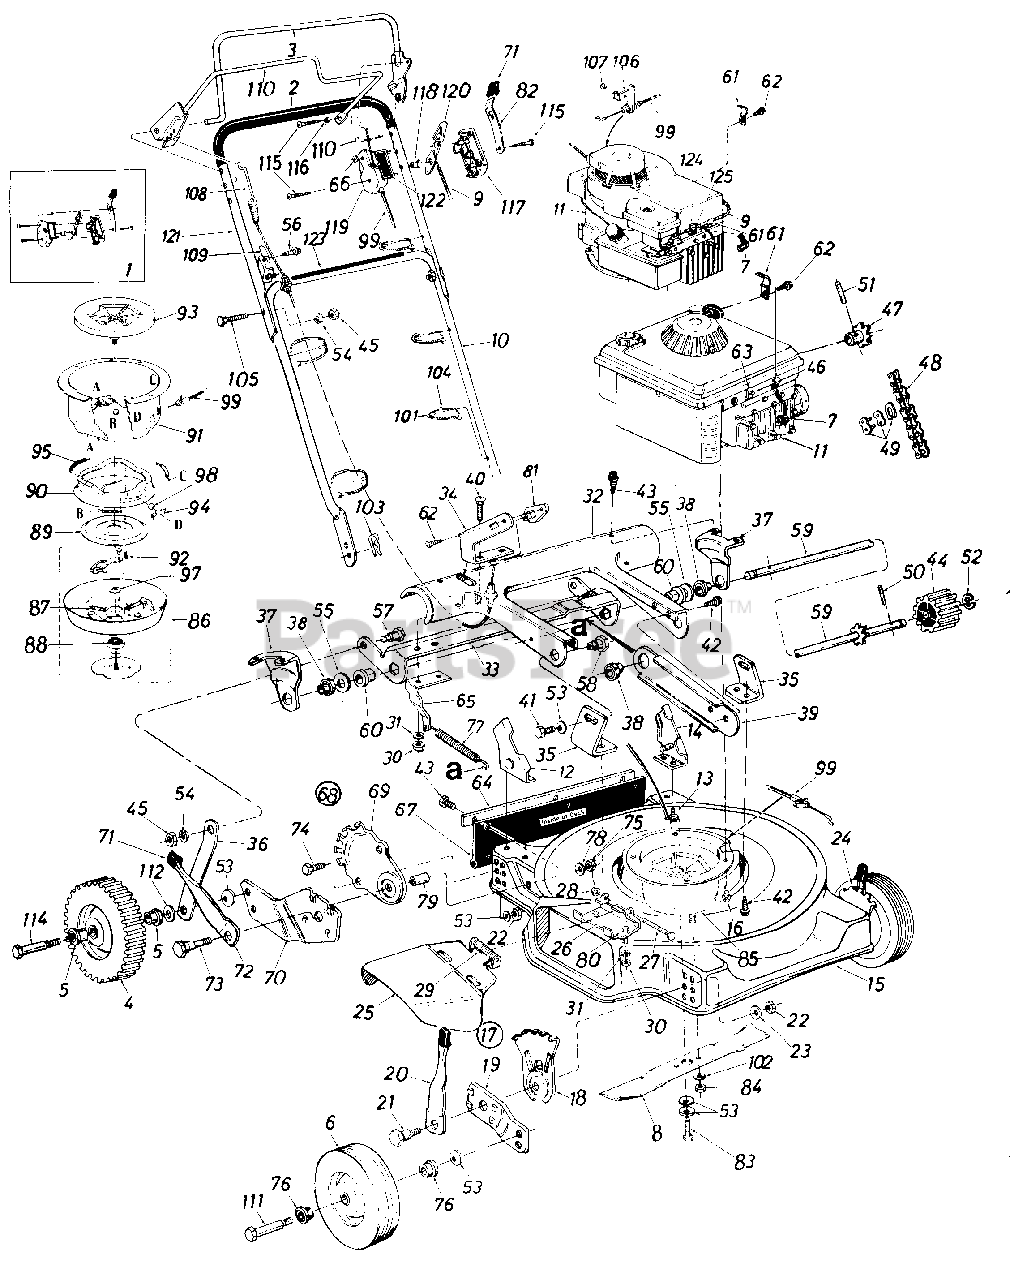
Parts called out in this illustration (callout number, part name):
1	Kit-Control Housing Comp.
3	Control Handle Ass'y.-L.H.
4	Rear Wheel Ass'y.-Comp. 8 x 1.75
5	Rear Wheel Brg.
7	Spark Plug Boot
8	22" Blade
9	Throttle Control Wire-53"
10	Lower Handle
11	Engine
12	Handle Brkt. Ass'y.-R.H.
13	Hex Wash. Hd. "B"-Tap Scr. 5/16-18 x .50" Lg.
14	Handle Brkt. Ass'y.-L.H.
15	22" Deck Ass'y.
16	Hex Wash. Hd. TT-Tap Scr. 3/8-16 x 1.00" Lg.
17	Height Adj. Ass'y. Comp.-R.H.
18	Height Adj. Plate
19	Pivot Bar
20	Spring Lever w/Knob
21	Shld. Bolt .500" Dia. x .375
22	Hex Nut 3/8-16 Thd.
23	Bell-Wash. .39" I.D. x 1.4"
24	Height Adj. Ass'y. Comp.-L.H.
25	Chute Deflector Ass'y. Comp.
26	Deflector Hinge Plate Ass'y.
27	Pivot Pin
28	Push Cap 1/4" Rod
29	Torsion Spring
30	Hex Nut 1/4-20 Thd.
31	L-Wash. 1/4" I.D.
32	Pinion Pivot Cover 22"
33	Cam
34	Engagement Arm-L.H.
35	Pivot Bracket
36	Link 4.58" x .88" Wide
37	Axle Brkt.
38	Flange Ball Brg. .500" I.D.
39	Brg. Support
40	Carriage Bolt 1/4-20 x .62"
41	Hex Bolt 3/8-16 x .50" Lg.*
42	Hex AB-Tap Scr. 1/4 x .62"
43	Hex Wash. Hd. AB-Tap Scr. 1/4" x.62" Lg.
44	13 Teeth-Drive Pinion
45	Hex Nut 5/16-18 Thd.
46	Hex B-Tap Scr. #10 x .62"
47	10 Tooth Sprocket Ass'y.
48	#48 Chain 1/2" Pitch 49 Links
49	Master Link
50	Spring Pin Spir. 3/16" Dia. x 1.25" Lg.
51	Spring Pin Spir. 3/16" Dia. x 1.00" Lg.
52	"E"-Ring For .500" Dia. Shaft
53	Bell-Wash. .400" I.D. x .88"
54	L-Wash. 5/16" I.D.
55	Fl-Wash. .531" I.D. x .930"
56	Hex AB-Tap Scr. 5/16 x .751
57	Shld. Bolt .437" I.D. x .162
58	Shld. Nut .625" Dia. x .165
59	Pinion Shaft w/7 T Sprocket
60	Flange Brg. .506" I.D.
61	Casing Clamp
62	Hex B-Tap Scr. #10 x .38"
63	Casing Clamp
64	Retaining Strip
65	Spring Bracket
66	Fl-Wash. .203 I.D. x .406
67	Rear Flap Ass'y.
68	Rear Height Adj. Ass'y. Comp.-R.H.
69	Index Plate
70	Pivot Bar-R.H.
71	Spring Lever Knob
72	Spring Lever
73	Shoulder Bolt .500" Dia. x .433" Lg.
74	Hex Bolt 3/8-16 x .75" Lg.
75	Hex Cent. L-Nut 5/16-18 Thd.
76	Front Wheel Bearing
77	Extension Spring 4.25" Lg.
78	Bell-Wash. .345" I.D. x .88"
79	Spacer .383" I.D. x .5031" O.D. x .562" Lg.
80	Hex Bolt 1/4-20 x .50" Lg.
81	Barrel Cable Hold-Down
82	Lockout Lever
83	Hex Bolt 3/8-24 x 2.00" Lg. (Grade 8)
84	Hex Nut 3/8-24 Thd. (Grade 8)
85	Blade Brake/Clutch Comp.
86	Clutch Blade Housing Ass'y.
87	Compression Spring .35" O.D. x 2.00" Lg.
88	Ball Brg. .669" I.D. x 1.574"
89	Clutching Cone
90	Brake Cup Cone
91	Clutch Housing
92	Hex Tap L-Scr. 1/4-20 x .75"
93	Fan Adapter
94	Ball Block
95	Extension Spring .35" O.D. x 1.75" Lg.
97	Fl-Wash. .690" I.D. x 1.060" O.D.
98	Steel Ball .500" Dia.
99	Clutch Cable-43"
101	Cable Anchor
102	L-Wash. 3/8" I.D.
103	Intern. Cot. Pin 5/16" Dia.
104	Cable Tie
105	Curved Carriage Bolt 5/16-18 x 1 38" Lg.
106	Cable Bracket
107	Pop Rivet .156" Dia. x .379
108	Clutch Cable w/Spring
109	Cable Mtg. Brkt.
110	Control Handle
111	Shld. Bolt .448 Dia. x 1.450
112	Fl-Wash. .531" I.D. x .93"
114	Shld. Bolt .498" Dia. x 1.64
115	Truss Mach. Scr. #12 x 1.50" Lg.
116	Spacer.23" I.D.
117	Control Panel Half
118	Control Disc Pin
119	Clutch Panel Half
120	Throttle Control Lever
121	Upper Handle (Chrome)
122	Control Label
123	Instruction Label
124	Casing Clamp
125	Hex AB-Tap Scr. #8 x .50"
